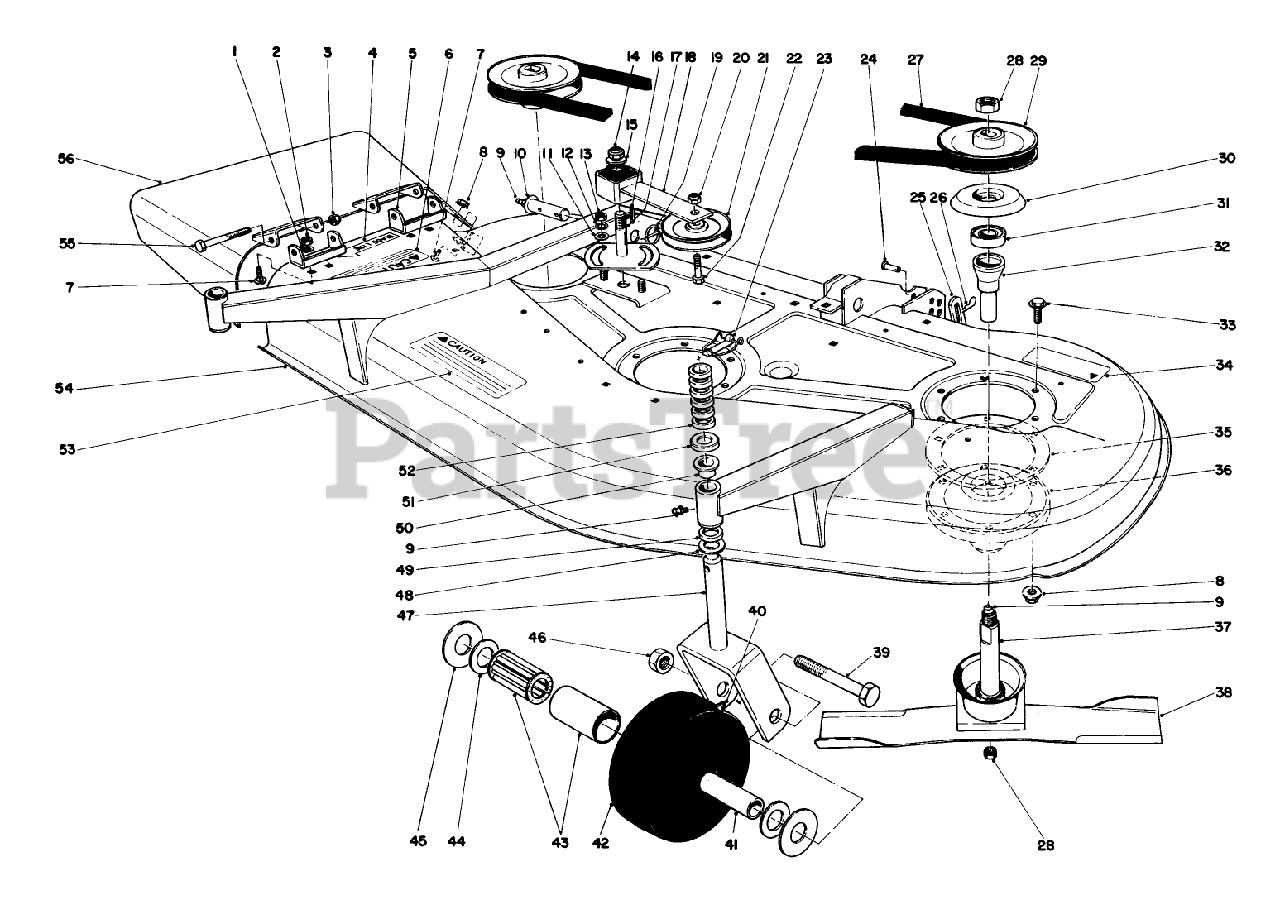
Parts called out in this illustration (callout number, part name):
1	WASHER-LOCK
2	NUT-HEX
3	NUT-HEX
4	DECAL - BLADE LINE
5	Bracket-Pivot
6	DECAL-CAUTION, DEFLECTOR
7	SCREW-CARR
8	NUT-HF
9	FITTING-GREASE
10	PIVOT PIN WA RO
11	WASHER-FLAT
12	WASHER-LOCK
13	NUT-JAM
14	NUT-LOCK, NI
15	WASHER-FLAT
16	KEY-SQUARE
17	PLATE-IDLER
18	IDLER ARM ASM
19	PIN-LYNCH
20	NUT-HEX
21	Idler Pulley
22	SCREW-HH
23	PIN-LYNCH
24	PIN-CLEVIS
25	LIFT BRKT LINKAGE R
26	PIN-HAIR
27	V-BELT
28	Locknut
29	Pulley
30	COVER-DUST
31	BEARING
32	SPACER-GREASE SHIELD
33	SCREW-HHF
34	DECAL-CAUTION, BLADE
35	SUPPORT-DECK, RING
36	Housing Assembly
37	SHAFT and SADDLE ASM
38	Blade
39	SCREW-HH
40	Fitting-Grease
41	SPANNER BUSHING
42	WHEEL
43	ROLLER BEARING
44	BEARING RETAINER
45	THRUST WASHER
46	NUT-LOCK
47	Castor Fork
48	WASHER-THRUST
49	SPACER
50	Bushing
51	CASTOR SLINGER
52	SPACER 1/2 IN
53	CAUTION DECAL
54	Housing (Incl. Ref. #50)
55	SCREW-HH
56	DEFLECTOR WA R
